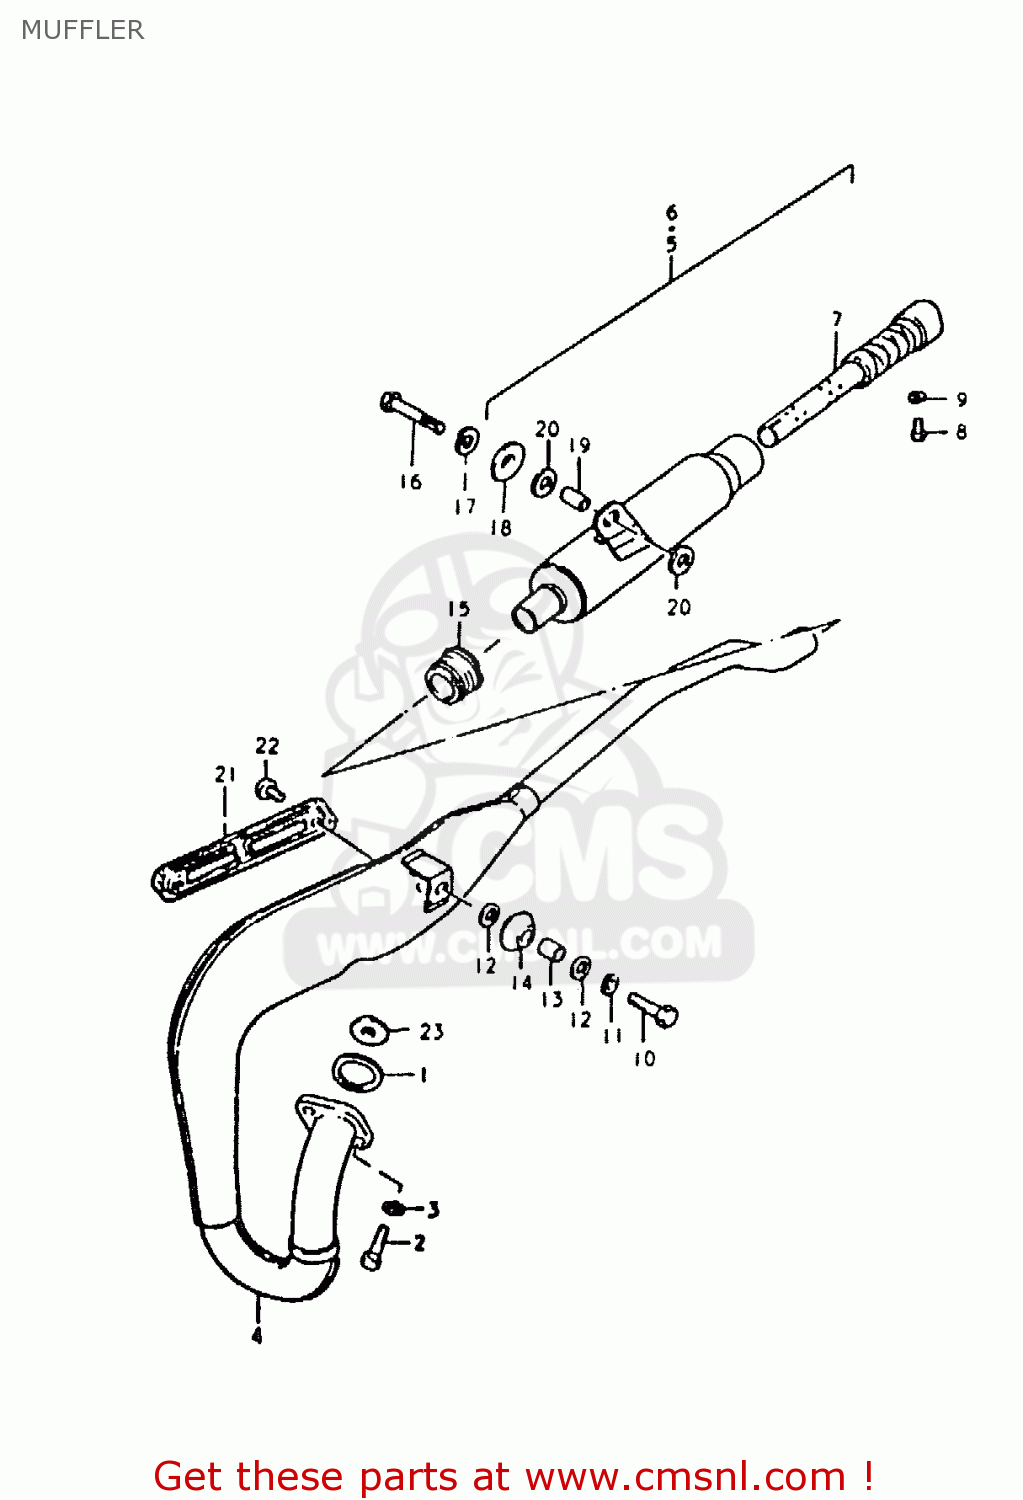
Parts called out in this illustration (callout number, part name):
1	GASKET,EXHAUST PIPE (NAS)
2	BOLT
3	LOCK WASHER
4	MUFFLER, 1ST
5	MUFFLER, 2ND
7	PIPE, BAFFLE
8	BOLT(5X8)
9	LOCK WASHER
10	BOLT (8X30)
11	LOCK WASHER
12	WASHER
13	SPACER (8X12X15)
14	DAMPER,MUFFLER,FR
15	CONNECTOR,MUFFLER
16	BOLT
17	LOCK WASHER
18	WASHER
19	SPACER (8.6X13.8X9)
20	CUSHION
21	COVER,MUFFLER
22	SCREW
